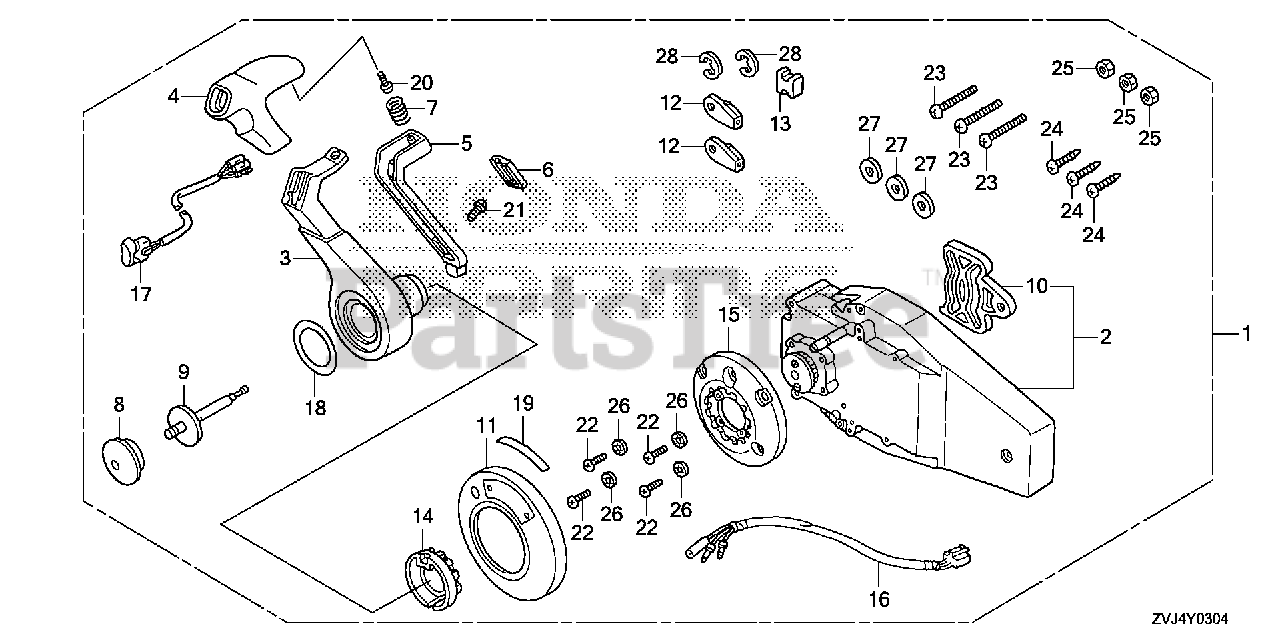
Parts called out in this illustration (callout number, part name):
1	BOX KIT, REMOTE CONTROL (FLUSH MOUNT)(R)
2	HOUSING ASSY., R. (INNER) (FLUSH MOUNT)
3	HANDLE, REMOTE CONTROL
4	COVER, GRIP
5	ARM, NEUTRAL LOCK
6	COVER, LOCK ARM
7	SPRING, NEUTRAL LOCK ARM
8	BUTTON, THROTTLE
9	SHAFT, THROTTLE BUTTON
10	PLATE, DWELL
11	COVER ASSY.
12	TERMINAL, CABLE
13	SPACER, CABLE CLAMP
14	HOLDER, NEUTRAL LOCK
15	BASE
16	SUB-HARNESS ASSY., POWER TRIM-TILT (C)
17	SWITCH ASSY., POWER TRIM-TILT (C)
18	MARK, HANDLE FLUSH MOUNT
19	MARK, FLUSH MOUNT
20	SCREW, PAN (5X16)
21	SCREW, TRUSS (4X12)
22	SCREW, PAN (5X30)
23	SCREW, PAN (6X35)
24	SCREW, TAPPING (6X30)
25	NUT, HEX. (6MM)
26	WASHER, LOCK (5MM)
27	WASHER, PLAIN (6MM)
28	E-RING (6MM)
